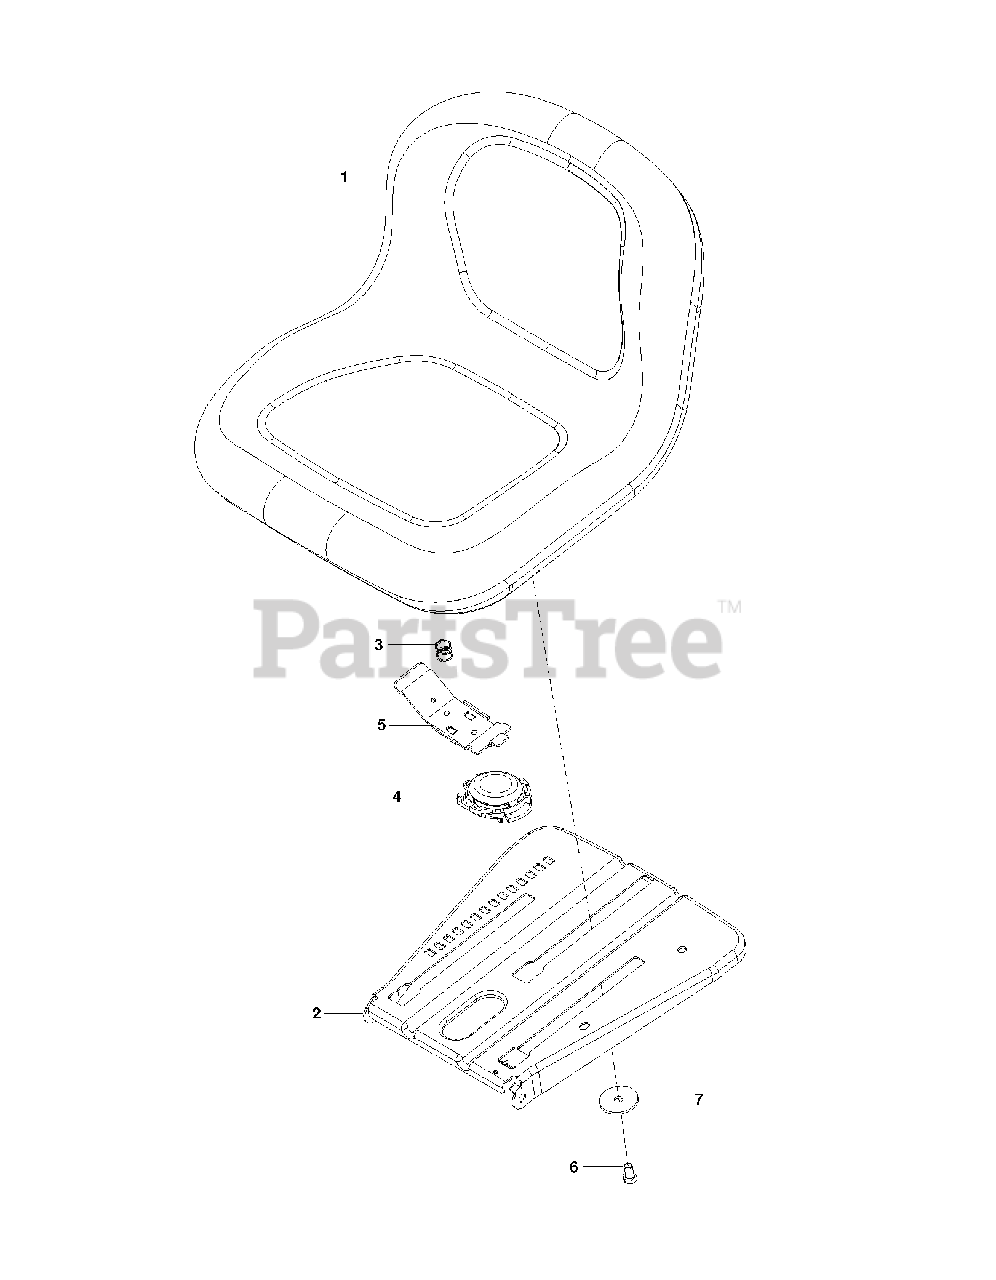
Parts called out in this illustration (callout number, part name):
1	RP SEAT, TH150, GREY, MILSCO
2	PAN.ASM.SEAT.3PT
3	SPRING.LATCH.SEAT.TEX
4	SWITCH, SEAT N/C
5	HANDLE.SLIDE.SEAT.TEX.BLACK
6	HCS 3/8-16 X 5/8 GR 5 ZD
7	WASHER, 3/8 SPEC
